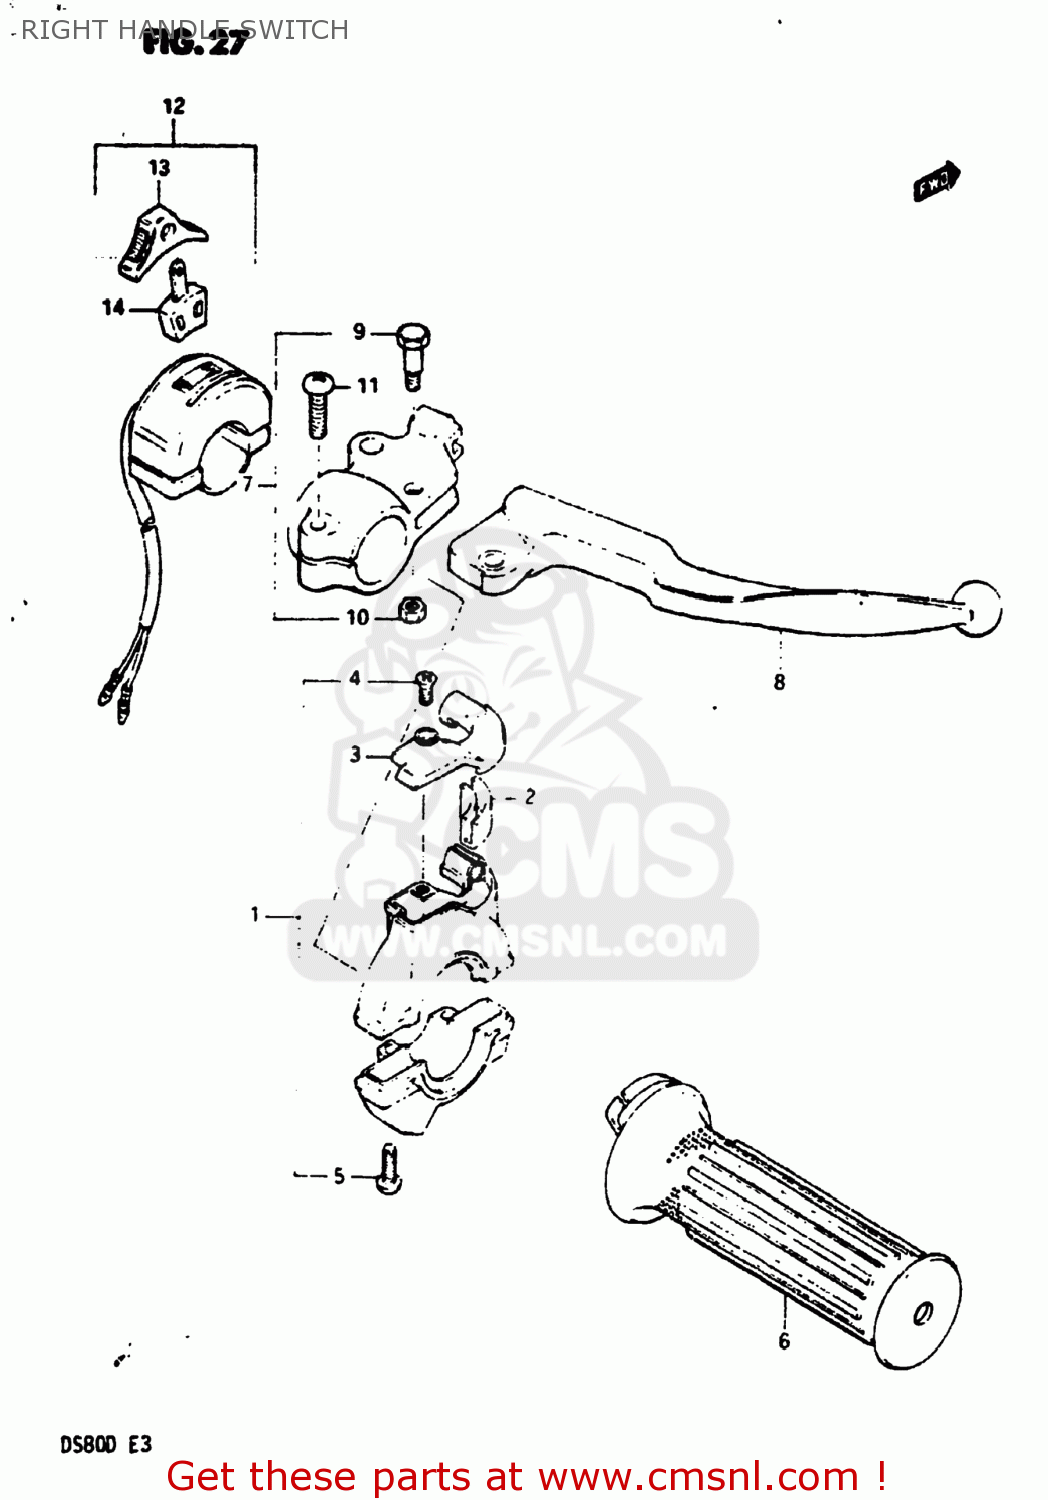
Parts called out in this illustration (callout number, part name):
1	CASE ASSEMBLY,THROTTLE
2	GUIDE PIECE,THROTTLE
3	COVER,THROTTLE CASE
4	SCREW 4X10
5	SCREW
6	GRIP,THROTTLE
7	LEVER ASSY,BRAKE
8	LEVER,BRAKE
9	BOLT,LEVER
10	NUT
11	SCREW
12	SWITCH ASSY,LIGHTING
13	KNOB,LIGHTING & DIMMER
14	BLOCK,LIGHTING/DIMMER
